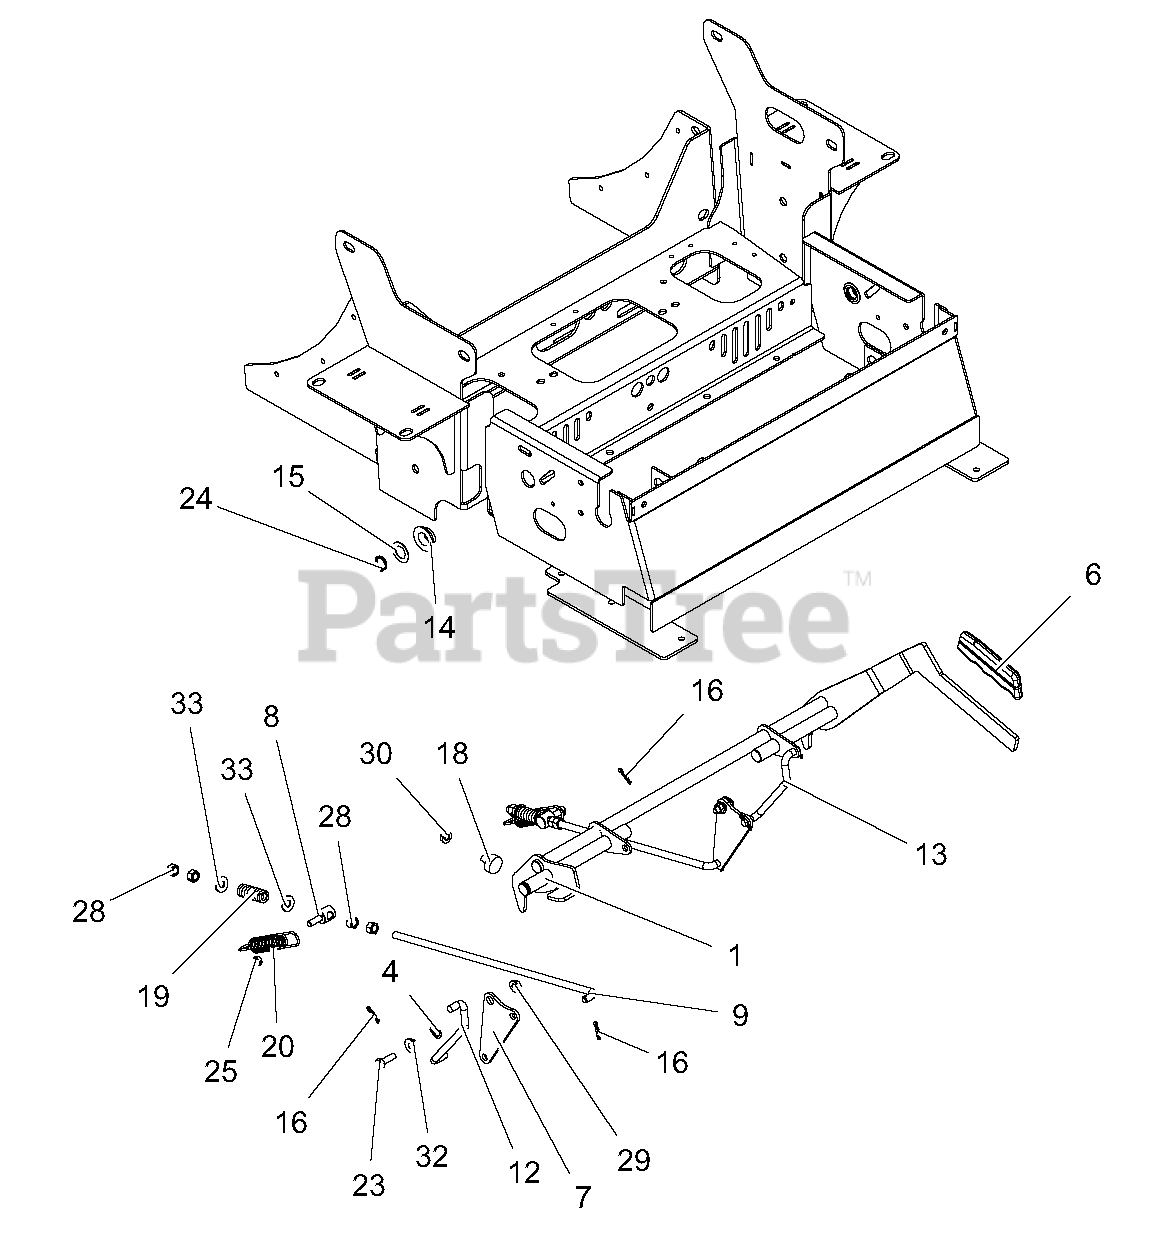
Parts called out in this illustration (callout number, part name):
1	WLDMT, PARKING BRAKE LEVER
4	WAVE WASHER .531X.781X.125 FH
6	GRIP, PARKING BRAKE (YELLOW)
7	PLATE, BRAKE PIVOT-BLACK
8	TRUNNION, .31-18
9	ROD, BRAKE ADJ.
12	LINKAGE, RH BRAKE ACTUATING
13	LINKAGE, LH BRAKE ACTUATING
14	BSHG, FLANGE .762 X 1.48 X .44 NYLON
15	WHST-HDND-THRST
16	PIN-HAIR, ENDRIES #25 YWZC
18	BUMPER, RUBBER
19	SPRG, COMPRESSION
20	SPRG, EXTENSION
23	BLT-HEX .31-18X1.00 GR5 YWZC
24	RG-RTNG-EXT .750x.078
25	@NUT-LK-CTR-JAM .31-18 YWZC
28	NUT-HEX .38-16 YWZC
29	@NUT, LK-TOP-FLG .312-18 YWZC
30	@NUT-SPNLK-FLG .312-18 YWZC
32	BSHG, FLG .32X.500.344X.880
33	@WSHR-FL-STL.38X.875X.083 YWZC
